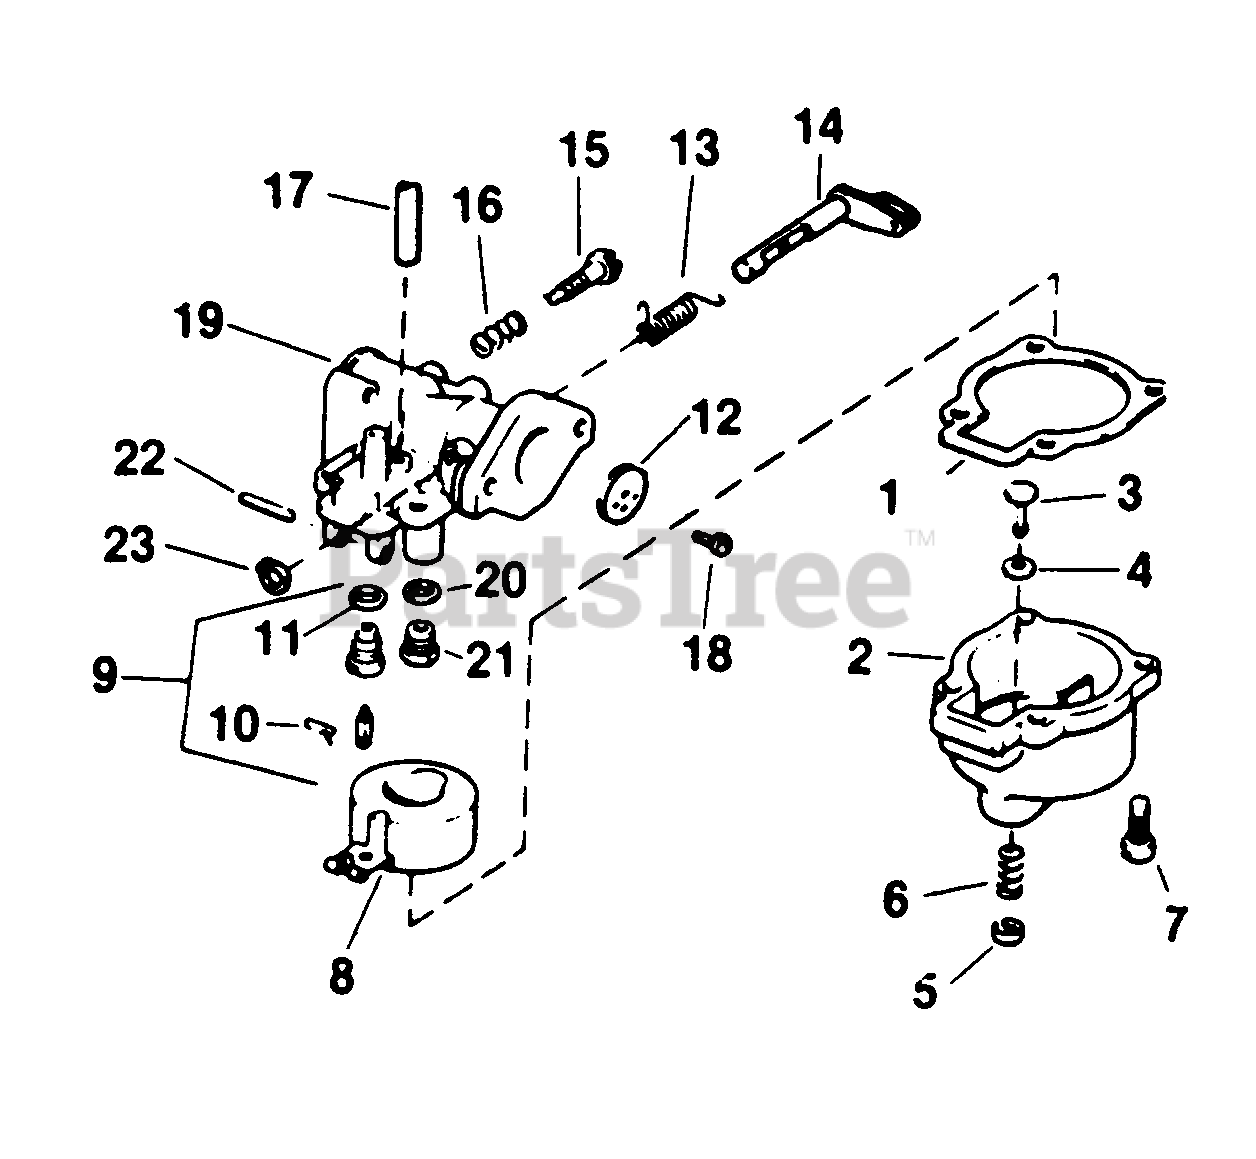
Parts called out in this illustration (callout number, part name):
1	Gasket
2	Float Chamber & Dump Valve Assy.
3	Valve Stem
4	Valve Seat
5	Valve Keeper
6	Valve Spring
7	Screw
8	Float & Arm Assy.
9	Float Valve & Seat Assy.
10	Clip
11	Washer
12	Disc.
13	Spring
14	Shaft
15	Screw
16	Spring
17	Fuel Hose
18	Screw
19	Carburetor Body Assy.
20	Washer
21	Plug
22	Float Pin
23	Grip Ring
